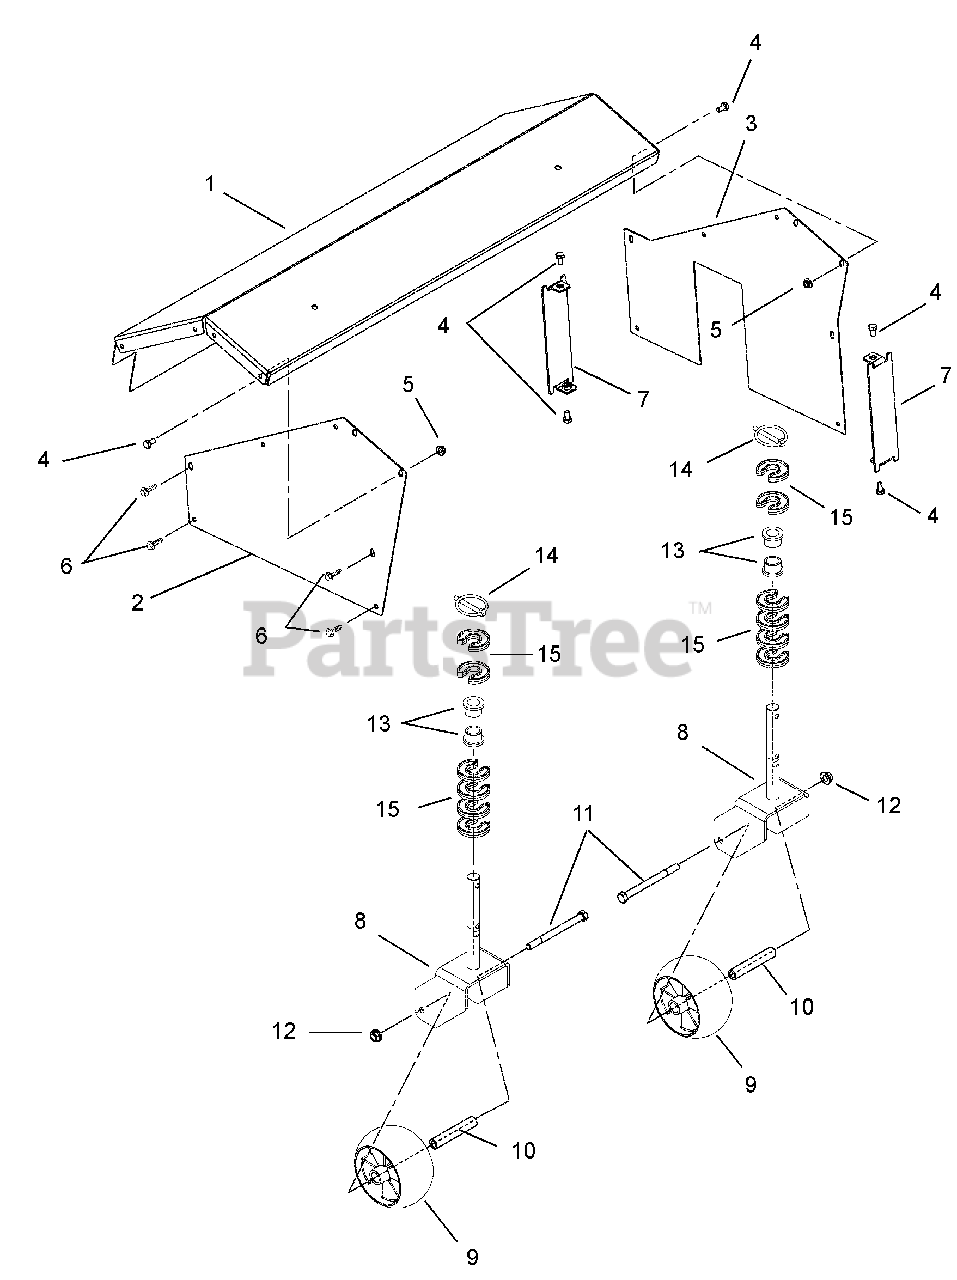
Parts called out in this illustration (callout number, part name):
1	Cover with Decals, 28" Brush
2	Cover, Right Hand Side – Brush
3	Cover, Left Hand Side – Brush
4	Bolt, Hex .25-20 x .50 Grade 5
5	Nut, Locking Top Flange .25-20
6	Screw, Tapping .25-20 x .50 Hex Washer Head
7	Cover, End
8	Fork, Caster
9	Wheel, Anti-Scalp
10	Spacer, Caster Wheel
11	Bolt, Hex .38-16 x 4.50 Grade 5
12	Nut, Locking Top Flange .38-16
13	Bushing, Flange .75 x .75 x 1.0
14	Pin, Lynch .25 x 1.25
15	Clip, HOC Fixed
